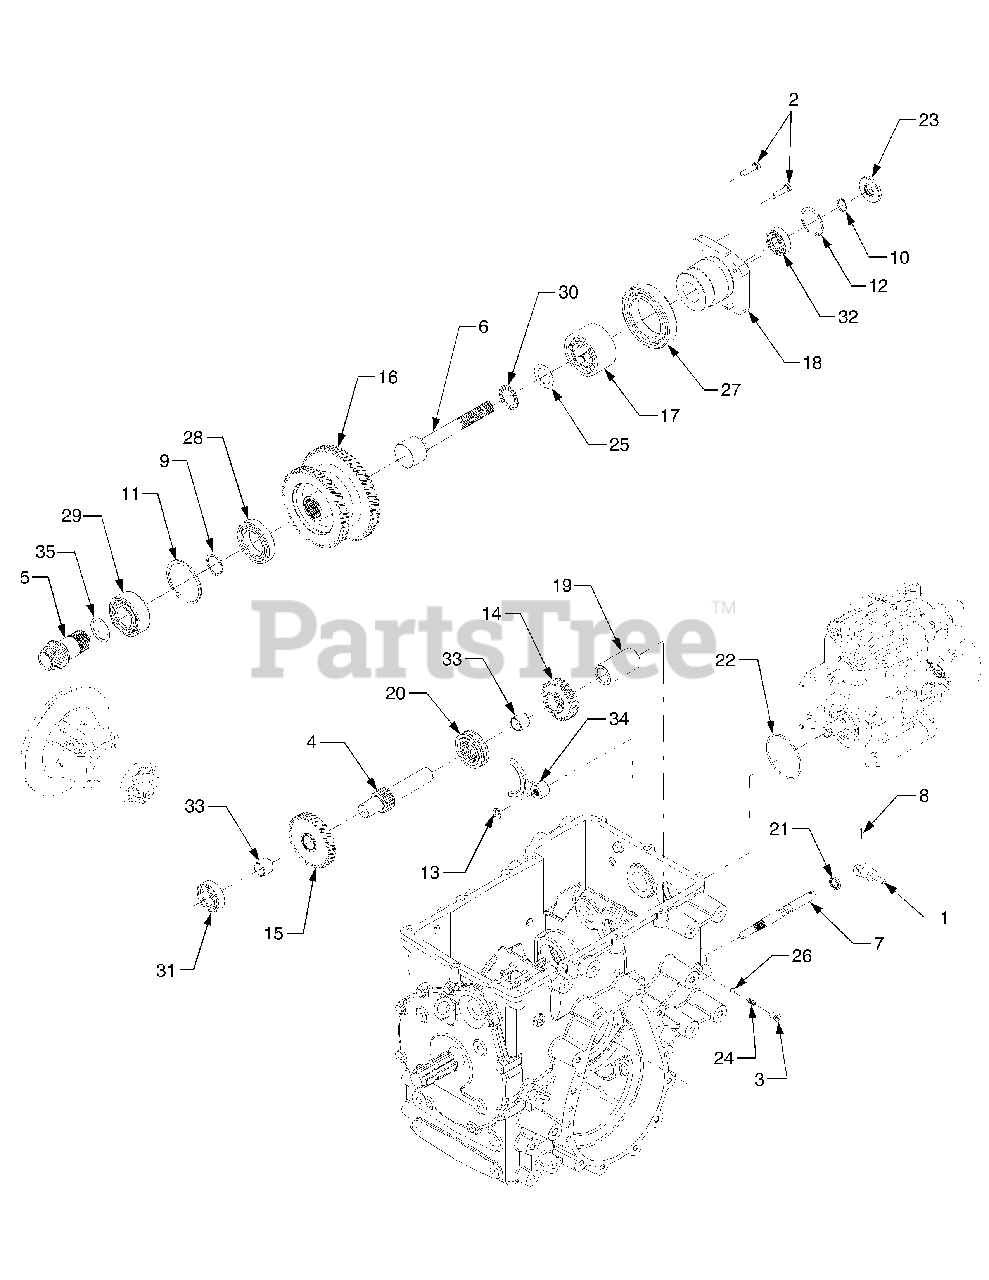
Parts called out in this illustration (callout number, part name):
1	Pin Assembly, 2 Speed
2	Screw, Hex Cap Lock, 5/16-18 x 1.25 GR5
3	Plug, Detent
4	Shaft, Motor
5	Shaft, Pinion, 16T
6	Shaft, 4WD
7	Shaft, Hi-Lo Detent Shift
8	Pin, Spirol, 3/16 x 1.25 HD
9	Ring, E Retaining
10	Ring, Retaining
11	Ring, Retaining
12	Ring, Retaining
13	Clip, Rotor
14	Gear, Drive Pinion, LO 24T:17T
15	Gear, Drive Pinion, HI 33T: 17T
16	Gear, Drive, LO:59T; HI 50T
17	Clutch, Overrunning
18	Cover, Front
19	Spacer, Drive
20	Collar, 2 Speed
21	Seal, Oil
23	Seal, Oil
24	Spring, Detent
25	Washer, Thrust
26	Ball, Detent
27	Bearing, Ball
28	Bearing, Ball
29	Bearing, Angular Contact Ball
30	Bearing, Thrust
31	Bearing, Ball
32	Bearing, Ball
33	Bearing, Sleeve
34	Yoke, 2 Speed
35	Washer, Flat, 1.38 x 1.8 x .004
